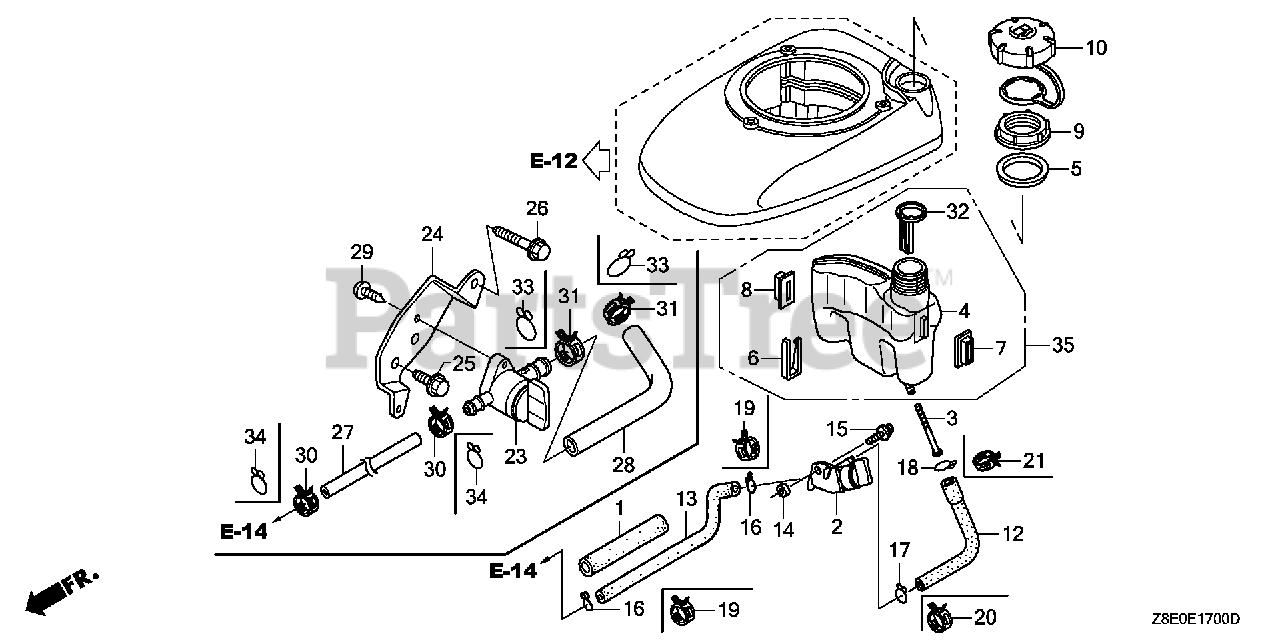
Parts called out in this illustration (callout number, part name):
1	RUBBER, SUPPORTER (107MM)
2	PETCOCK ASSY.
3	FILTER, FUEL
4	TANK, FUEL
5	SEAL, FUEL FILLER NECK
6	CLIP, TANK MOUNTING
7	RUBBER A, TANK MOUNTING
8	RUBBER B, TANK MOUNTING
9	NUT, TANK MOUNTING
10	CAP ASSY., FUEL TANK
12	TUBE, FUEL TANK (FKM)
13	TUBE, FUEL (FKM)
14	COLLAR, FUEL PETCOCK
15	SCREW-WASHER (5X10)
19	CLIP, TUBE (D8)
20	CLAMP, TUBE (D10)
21	CLAMP, TUBE (D12)
32	GAUGE, FUEL LEVEL
